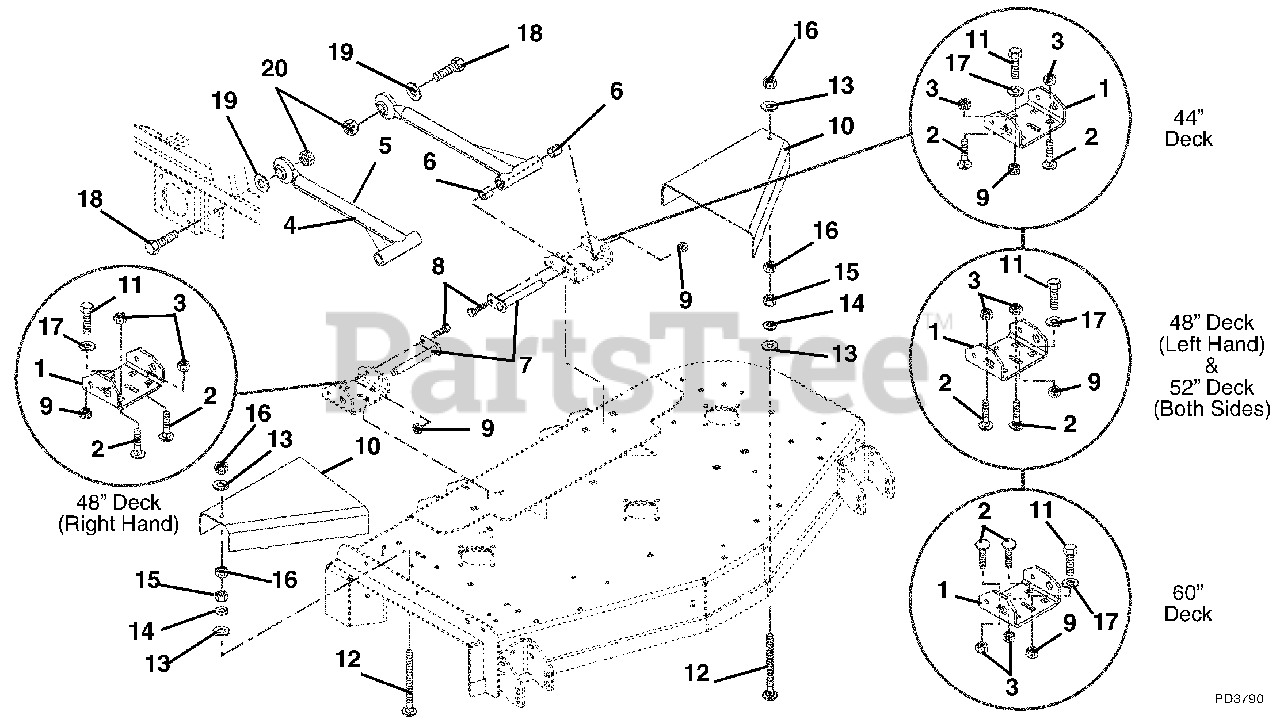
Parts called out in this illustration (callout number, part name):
1	Bracket, Mower Mounting (Rear)
2	Bolt-Round Head Square Neck .50-13 x .75 Grade 5
3	Nut, Locking Center Jam .50-13
4	Assembly, Mower Mounting
5	Mower Mounting Arm
6	Bearing, .75 x .875 x 1.00
7	Weldment, Mower Mounting Pin
8	Bolt-Hex .38-16 x .75 Grade 5
9	Nut-Locking-Top-Flange .38-16
10	Guard, Pulley (042, 043)
10	Guard, Pulley Right Hand (044)
10	Guard, Pulley Left Hand (044)
10	Guard, Pulley Left Hand (051)
10	Guard, Pulley Right Hand (051)
11	Bolt-Hex .38-16 x 1.00 Grade 5
12	Bolt-Round Head Square Neck Full Thread .312-18 x 3.50 (042, 043,
12	Bolt-Round Head Square Neck Full Thread .312-18 x 3.50
13	Washer-Flat-Steel .344 x .688 x .065 (042, 043, 044, 054,
13	Washer-Flat-Steel .344 x .688 x .065 (051, 055)
14	Washer-Locking .31 x .078 (042, 043, 044, 054, 310, 311)
14	Washer-Locking .31 x .078 (051, 055)
15	Nut-Hex .31-18 (042, 043, 044, 054, 310, 311)
15	Nut-Hex .31-18 (051, 055)
16	Nut-Locking-Center .31-18 (042, 043, 044, 054, 310, 311)
16	Nut-Locking-Center .31-18 (051, 055)
17	Washer-Flat-Steel .406 x .812 x .065
18	Bolt-Hex .875-9 x 2.75 Grade 5
19	Washer-Flat-Steel .875 x 1.50 x .120
20	Nut-Locking-Center .875-9
